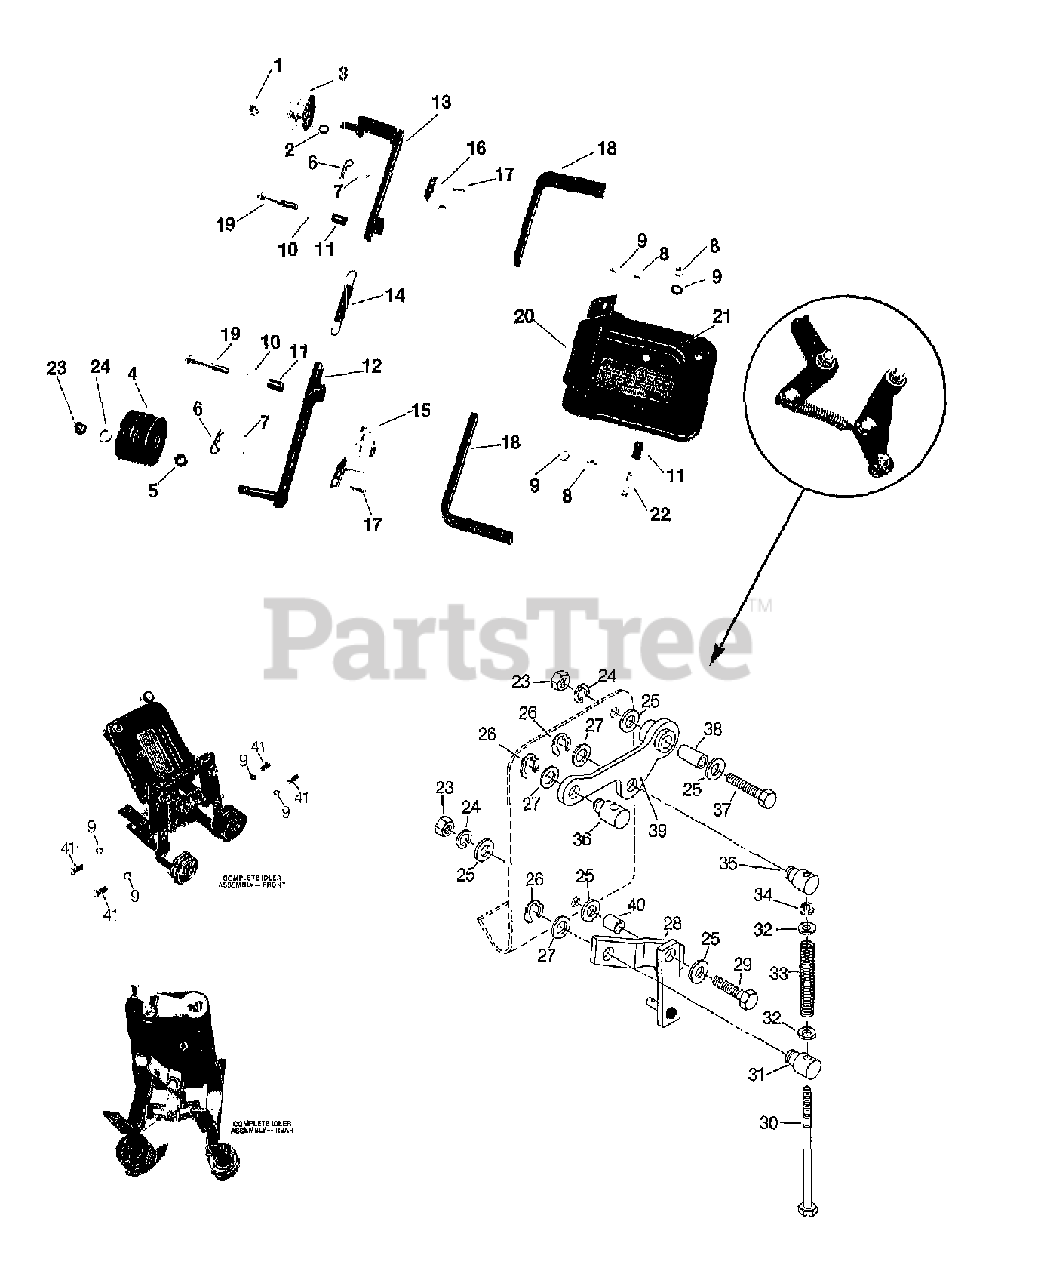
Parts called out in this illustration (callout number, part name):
1	LOCKNUT-hex, 3/8"-16
2	BUSHING-reverse idler pulley
3	PULLEY- Idler, reverse tiller direction
4	PULLEY-idler, forward tiller direction
5	SPACER
6	HITCH PIN
7	WASHER -plain, 1/4"
8	NUT-hex, 5/16"-18
9	LOCKWASHER-5/16"
10	WASHER-plain, 5/16"
11	PIVOT BUSHING
12	IDLER ARM-left, forward tiller direction
13	IDLER ARM-right, reverse tiller direction
14	SPRING
15	FORWARD LINK
16	REVERSE LINK
17	PIN
18	MOUNTING BAR
19	BOLT- idler arm, 5/16-18 x 2"(Grade 5)
20	SHIFTING BASE
21	DECAL-safety (warning instructions on belts/pulleys)
22	BOLT- hex head, 5/16"-18 x 1 1/4"
23	NUT- hex, 3/8"-16
24	LOCKWASHER-3/8"
25	SPACER - bushing
26	RETAINING RING
27	WASHER-pivot
28	BELLCRANK
29	BOLT- hex head, 3/8"-16 x 1 1/4"
30	ADJUSTMENT BOLT
31	PIVOT-lower
32	WASHER-(between lower pivot and spring, and between spring and retaining ring)
34	RETAINING RING
35	PIVOT-upper
36	PIVOT-
37	BOLT-hex head, 3/8"-16 x 1 1/2"
38	BUSHING -rod crank
39	ROD CRANK
40	BUSHING- bellcrank
41	BOLT-hex head, 5/16"-18 x 1"
